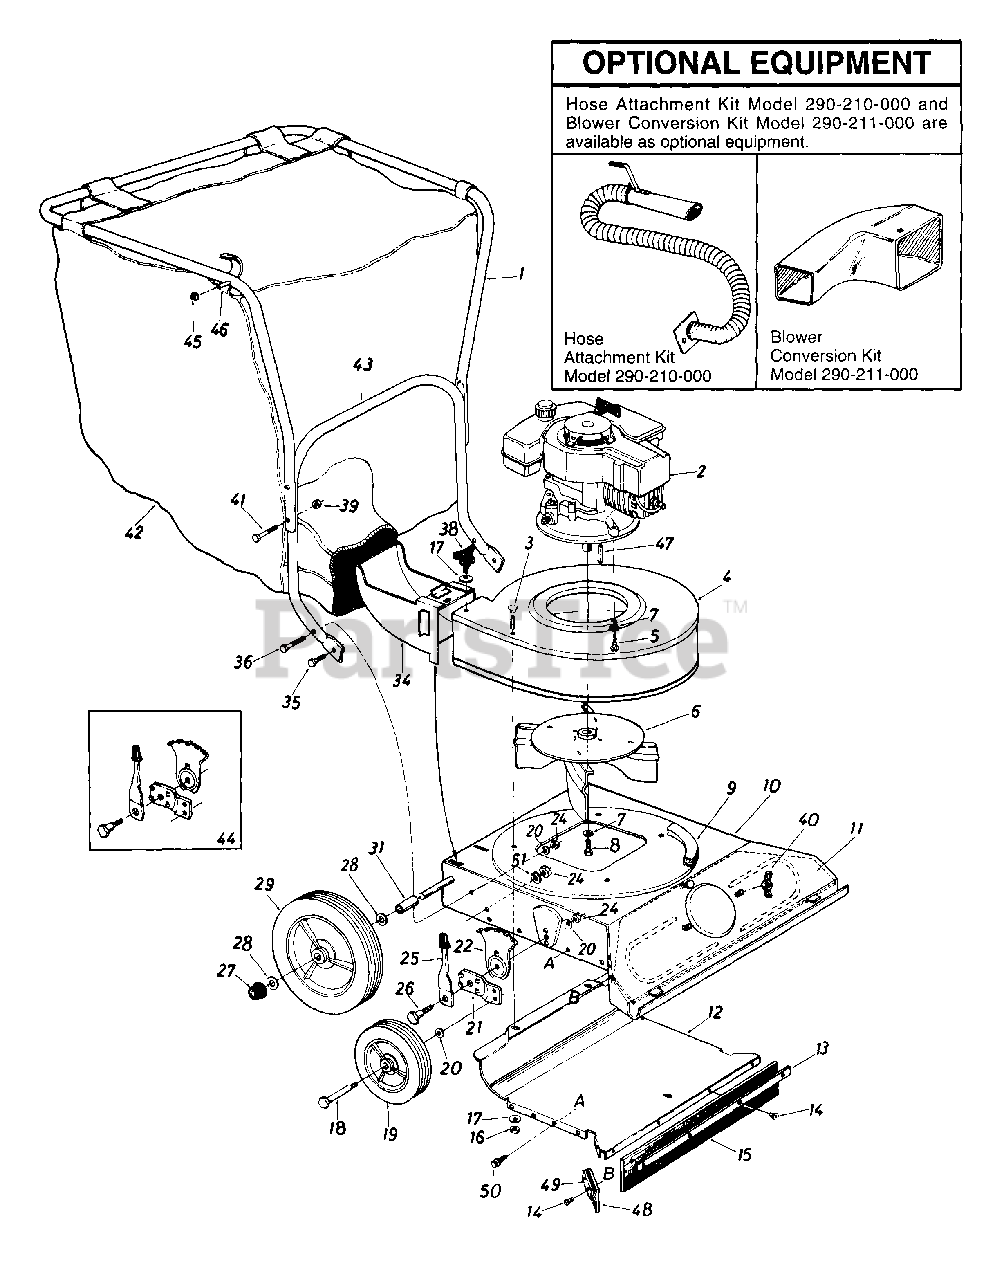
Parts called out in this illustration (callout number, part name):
1	Upper Handle
2	Engine
3	Carriage Bolt 5/16-18 x .62" Lg.
4	Blower Housing Ass'y.
5	Hex Tap Scr. 3/8-16 x 1.0" Lg.
6	Impeller Ass'y.
7	L-Wash. 3/8" I.D.
8	Hex Bolt 3/8-24 x 1.0" Lg. w/Patch
9	P.V.C. Foam Strip-12"
10	Vacuum Deck Ass'y.
11	Front Baffle Ass'y.
12	Lower Baffle Ass'y.
13	Wiper Retaining Strip
14	Pop Rivet .188" Dia.
15	Nozzle Wiper Rear
16	Hex Nut 5/16-18 Thd.
17	Bell-Wash. .34" I.D. x.87" O.D.
18	Shld. Bolt .498" Dia. x 1.45" Lg.
19	Front Wheel Ass'y. Comp.
20	Bell-Wash. .39" I.D. x 1.12" O.D.
22	Index Plate
24	Hex Nut 3/8-16 Thd.
25	Spring lever Assy. w/Knob
26	Shoulder Bolt .5" Dia. x 7/16" Lg.
27	Push Cap .5" Rod (Black)
28	Fl-Wash. 1/2" I.D. x 1.0" O.D. x .06"
29	Rear Wheel Ass'y. Comp.
31	Wheel Spacer 1/2" I.D, x 15/16"
34	Air Duct Ass'y.
35	Hex Bolt 3/8-16 x .75"
36	Hex Bolt 3/8-16 x 1.5"
38	Hand Knob
39	Hex L-Nut 1/4-20 Thd.
40	Wing Nut 1/4-20 (Plastic)
41	Hex Bolt 114-20 x 1.75"
42	Vacuum Bag (6.6 Bushel)
43	Lower Handle
44	Height Adj. Ass'y. Comp.-R.H.
45	Push Speed Nut .25" Dia.
46	Stud 9 in .25" Dia. x 1.75" Lg.
47	Sq. Key 3/16" x 1" Lg.
48	Nozzle Wiper Side
49	Wiper Retaining Strip
50	Hex Self-Tap Scr. #10
51	L-Wash. 3/8" I,D.
